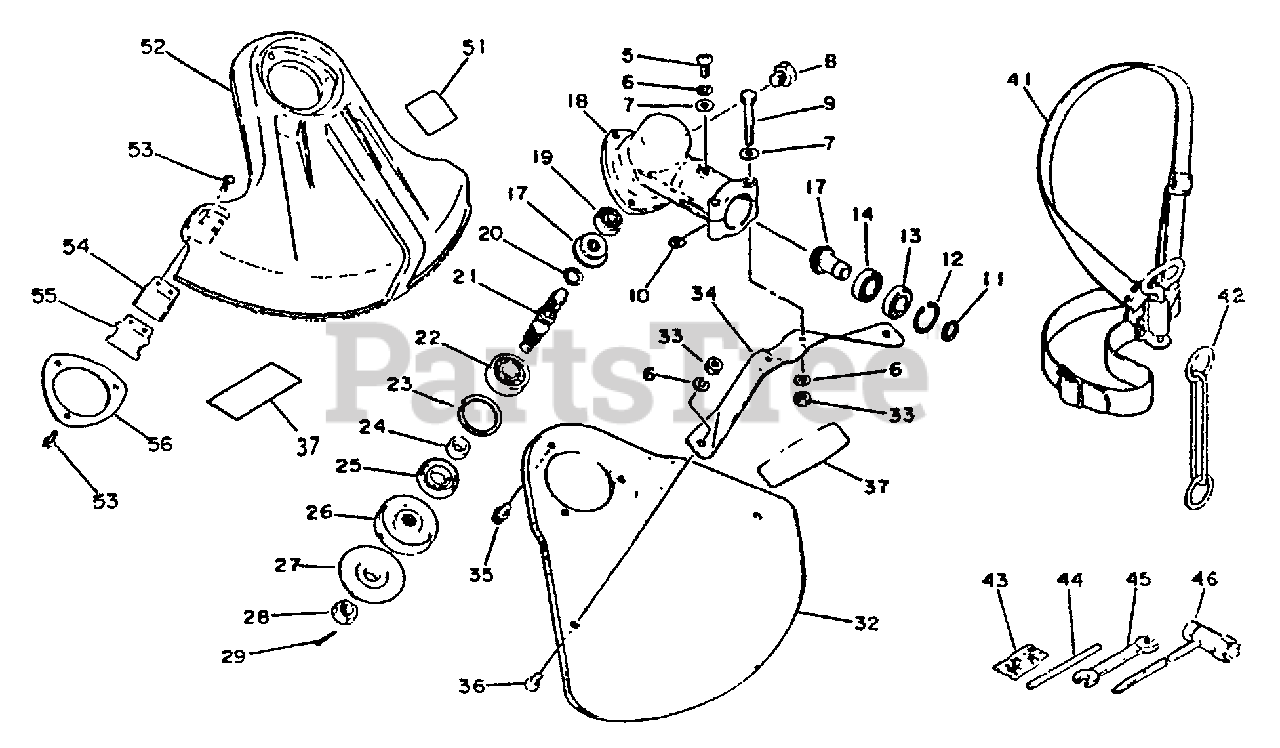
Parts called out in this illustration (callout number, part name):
5	SCREW 5×10
6	WASHER, SPRING 5
7	WASHER, FLAT 5.5×10×0.8
8	BOLT 8×8 SP
9	BOLT 5×35 SP
11	RING, SNAP Ø12
12	RING, SNAP Ø22
13	BEARING, BALL 6900Z
14	BEARING, BALL 6900
17	GEAR SET
18	HOUSING, GEAR CASE
19	BEARING, BALL 609
20	RING, SNAP Ø10
21	SHAFT, GEAR
22	BEARING, BALL - 6201 C3
23	RING, SNAP Ø32
24	SPACER 11.8×15×9
25	SEAL, OIL 22
26	PLATE, ADAPTER - UPPER
27	PLATE, ADAPTOR - LOWER
29	PIN, COTTER 2×22
32	SHIELD ASSY
33	NUT M5
34	BRACKET, SHIELD MOUNTING
35	SCREW 5×10
36	SCREW 5×8
37	LABEL - ECHO
41	SHOULDER STRAP ASSY
42	HOOK
43	PIN, COTTER 2×22 (PKG. OF 10)
44	TOOL, LOCKING 5×120 MM
45	SPANNER 8×10
46	T-WRENCH 17x-19 L200
51	LABEL - CAUTION
52	SHIELD ASSY
53	SCREW 5×16
54	KNIFE, TRIMMER LINE
54	CUTTER, LINE
55	PROTECTOR
56	PLATE, SHIELD Ø49.5 MM
